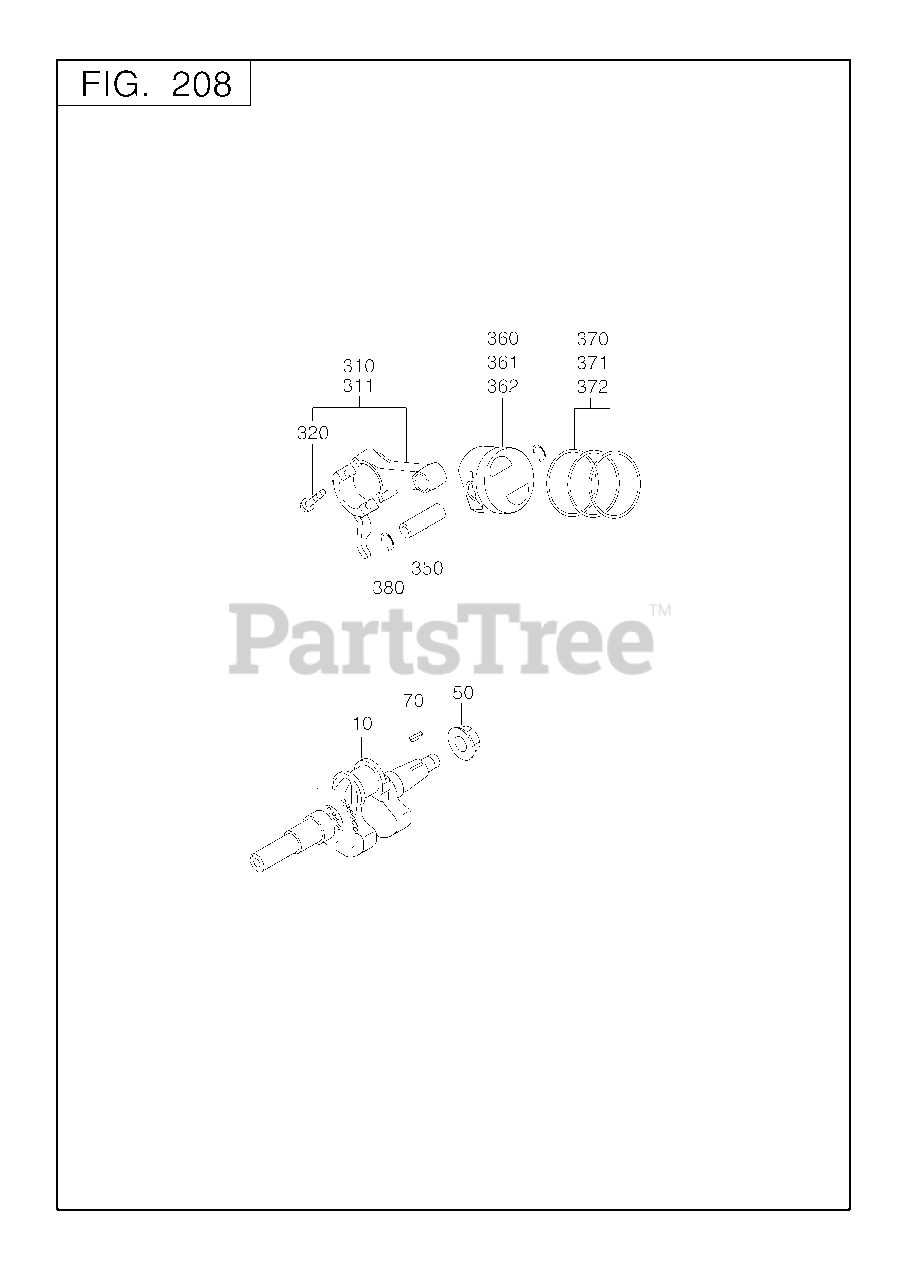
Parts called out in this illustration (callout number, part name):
310	CONNECTING ROD AY
311	CONNECTING ROD AY
320	CONNECTING ROD BOLT
370	PISTON RING SET
371	PISTON RING SET
372	PISTON RING SET
